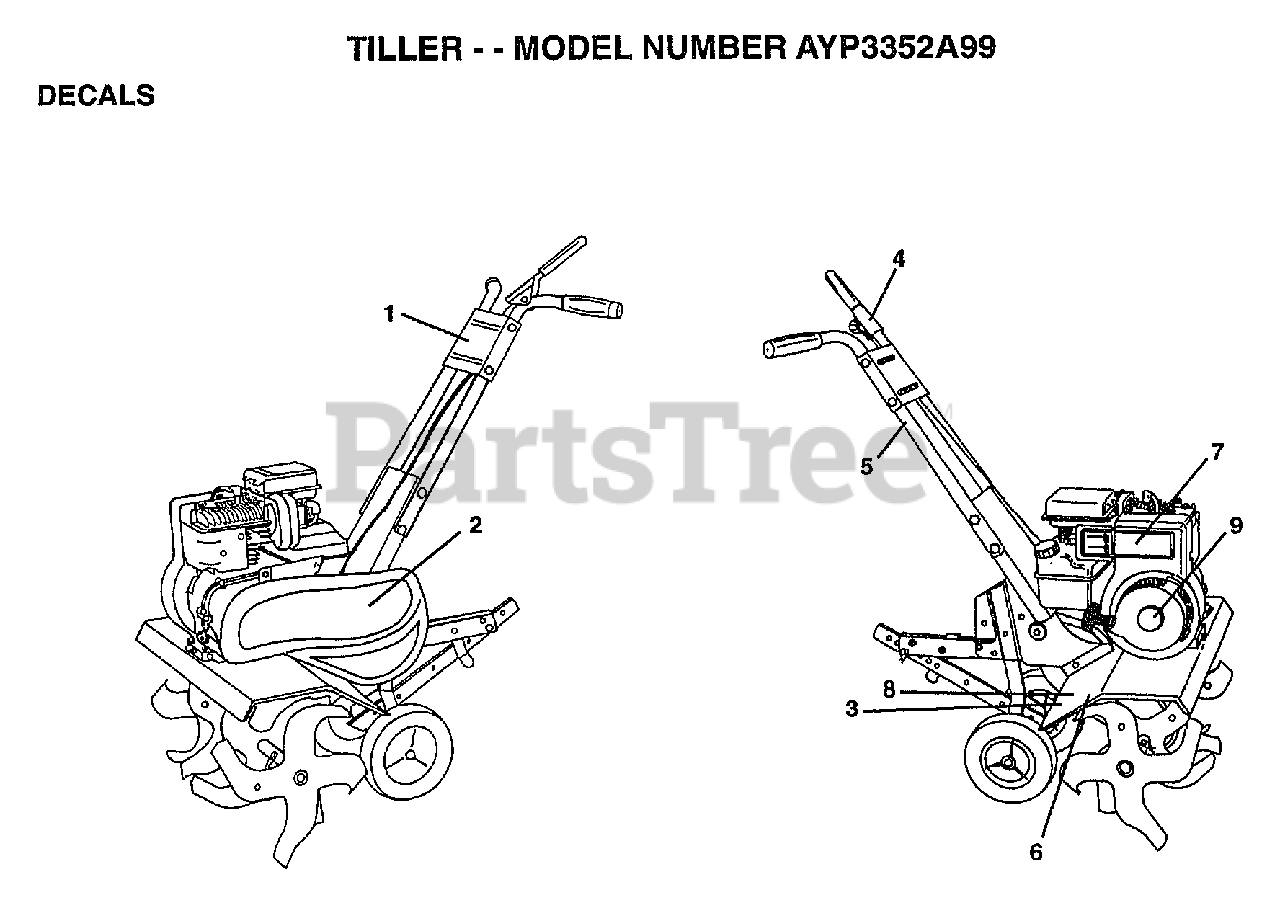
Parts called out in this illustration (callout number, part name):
1	DECAL.CNTRL.PNL.5
2	DECAL, LOGO
4	DECAL TI
5	DECAL TI
6	DECAL.TINE.SHIELD
8	DECAL TI
